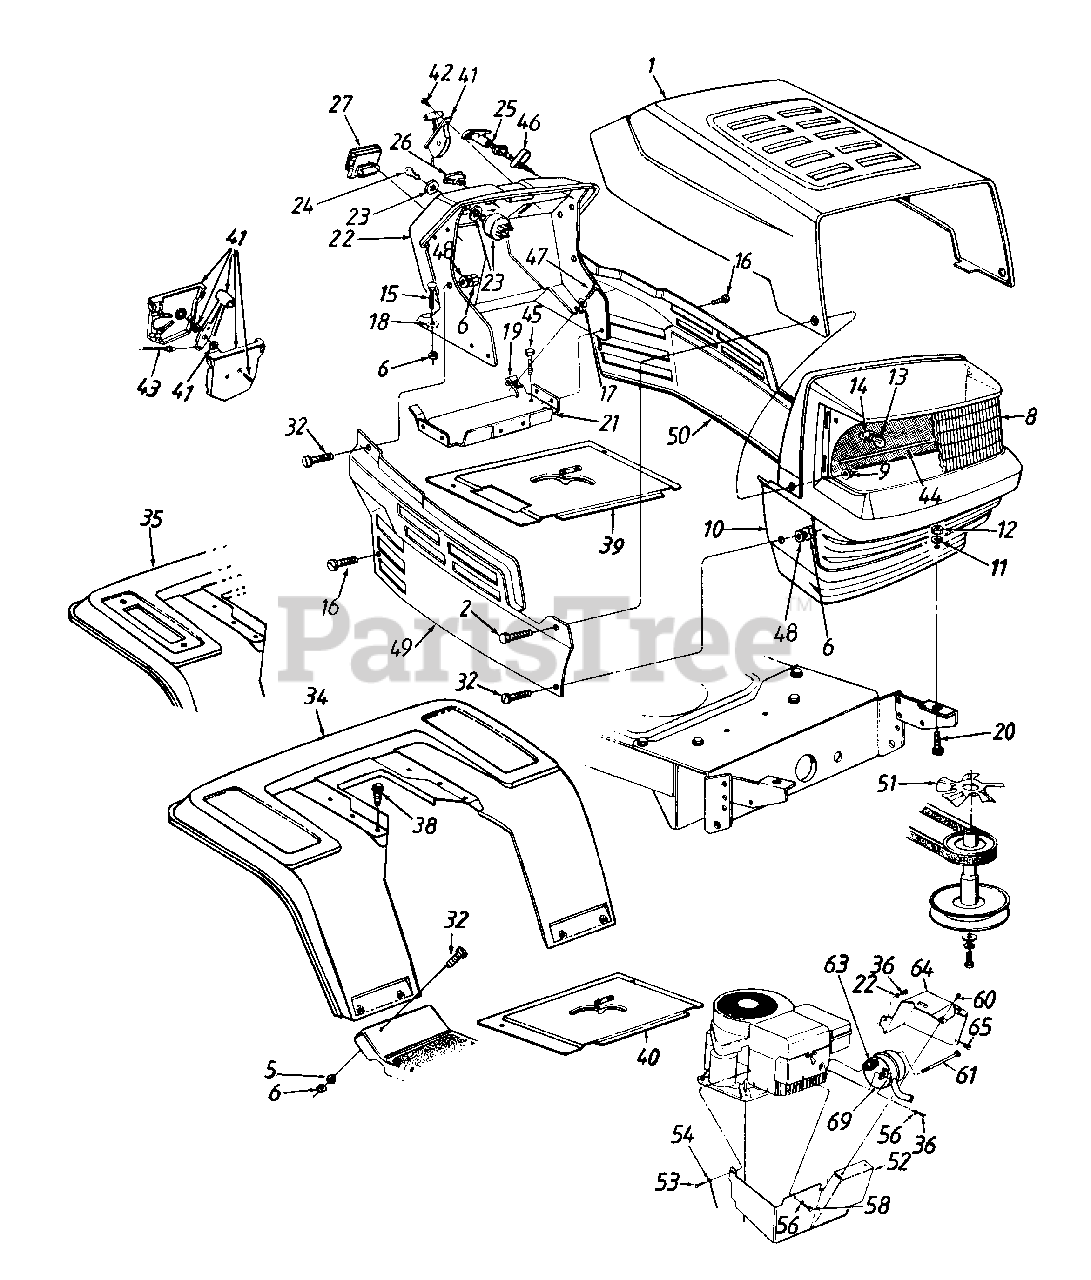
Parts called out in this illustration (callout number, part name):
3	Fl-Wash. .28" I.D. x .75" O.D.
6	Hex Nut 1/4-20 Thd.
8	Headlight Lens
9	Flange L-Nut 1/4-28 Thd.
10	Grille
11	Fl-Wash. .344" I.D. x 1" O.D.
12	Hex Nut 5/16-18 Thd.
13	Lamp
14	Socket
15	Carriage Bolt 1/4-20 x .75" Lg.
16	Hex Wash. Hd. TT-Tap Scr. 1/4-20 x .5" Lg.
17	Fl-Wash. .281" I.D. x .73" O.D.
18	Bolt Retainer 1/4" I.D.
19	Speed Nut 1/4-20 Thd.
20	Hex Bolt 5/16-18 x .75" Lg.
23	Ignition Switch
24	Ignition Key
25	Choke Control
26	Light Switch
27	Ammeter
32	Truss Mach. Scr. 1/4-20 x .5" Lg.
41	Throttle Box Ass'y.
42	Truss Mach. AB-Tap Scr. #10 x .5" Lg.
43	Throttle Control Wire
44	Grille Reflector Label
45	Hex Wash. Hd. B-Tap Scr. 5/16-18 x .5" Lg.
46	Choke Retainer
47	Hex TT-Tap Scr. 1/4-20 x .75" Lg.
48	Bell-Wash. 1/4" I.D.
52	Muffler Heat Shield-Front
53	Truss Mach. Scr. 5/16-18 x .75" Lg.
54	Ground Wire
56	Spr. Wash. 1/4" I.D.
58	Hex Bolt 1/4-20 x 3/8" Lg.
60	Hex B-Tap Scr. #10 x .38" Lg.
61	Shoulder Bolt
63	Exhaust Gasket
69	Muffler
70	L-Wash. 1/4" I.D.
